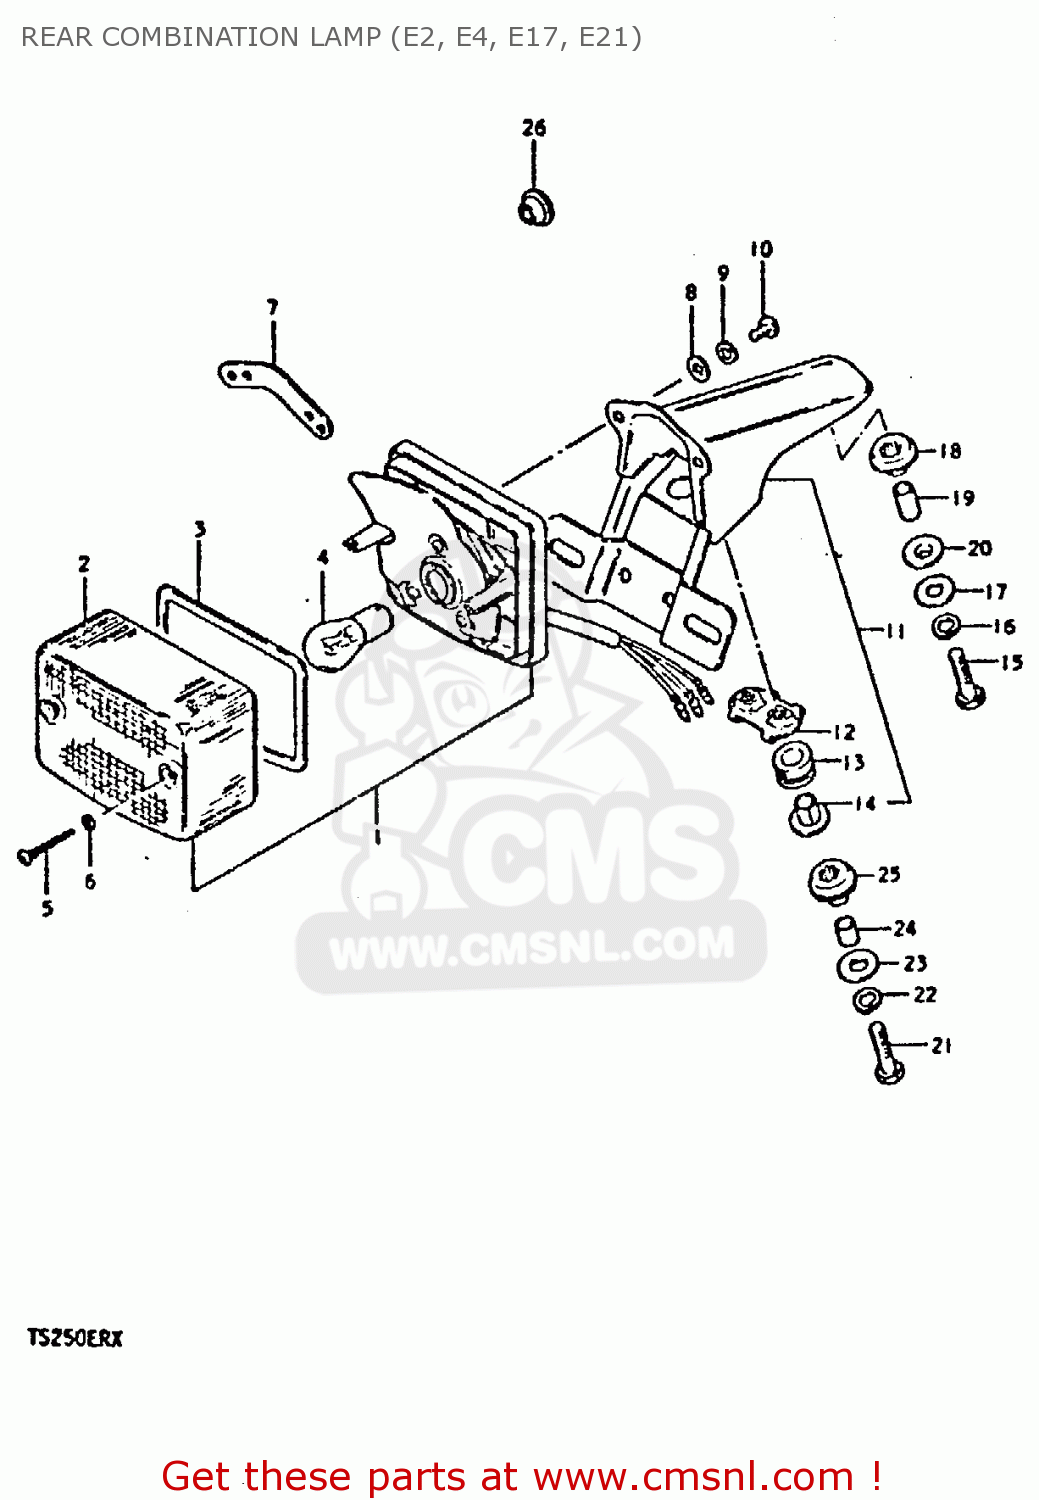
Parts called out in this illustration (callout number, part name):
1	LAMP UNIT, TAIL
2	LENS
3	GASKET (NAS)
4	BULB (6V,21/5W)
5	BOLT
6	GASKET (NAS)
7	PLATE,REAR COMBINATION LAMP
8	WASHER
9	LOCK WASHER
10	SCREW
11	BRACKET ASSY
12	PLATE
13	CUSHION
14	SPACER
15	BOLT
16	LOCK WASHER
17	WASHER (6.5X20X1.2)
18	CUSHION
19	SPACER
20	CUSHION
21	BOLT
22	LOCK WASHER
23	WASHER (6.5X20X1.2)
24	SPACER
25	CUSHION
26	GROMMET
